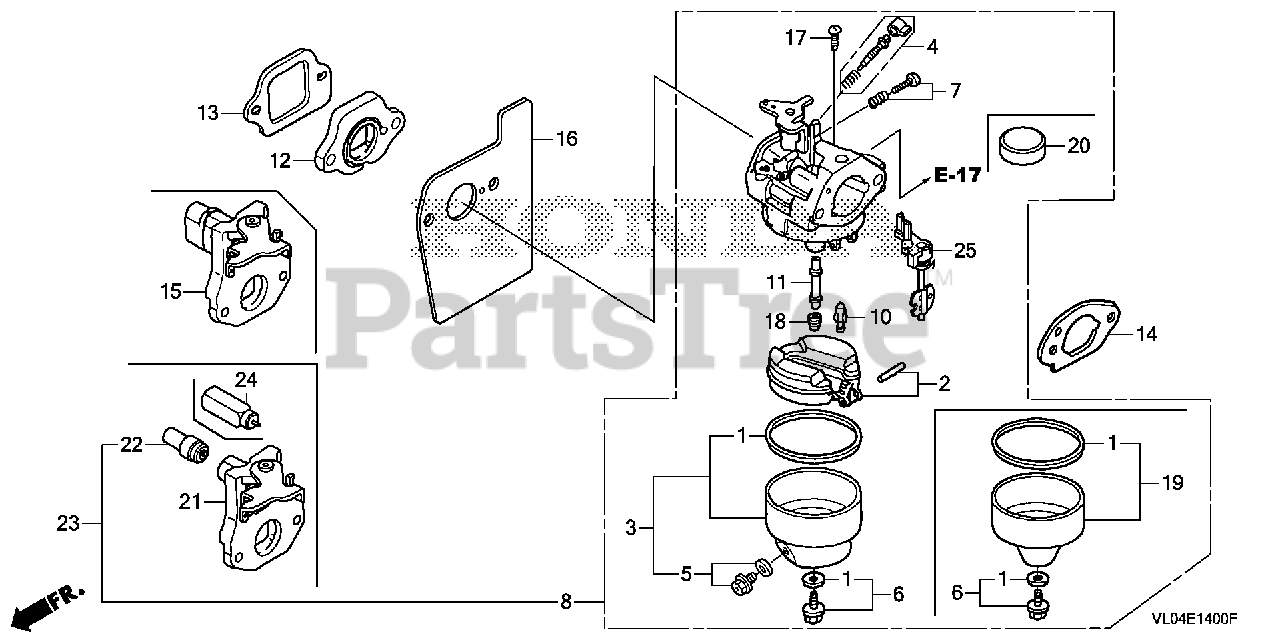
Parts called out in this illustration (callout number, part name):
1	GASKET SET
4	SCREW SET (CARBURETOR NO.)
6	SCREW SET
7	SCREW SET (THROTTLE STOP) (CARBURETOR NO.)
8	CARBURETOR ASSY. (BB75J A)
10	VALVE, FLOAT
11	NOZZLE, MAIN (CARBURETOR NO.)
13	GASKET, INSULATOR
14	GASKET, CARBURETOR (CHOKE SIDE)
16	GUIDE, AIR
17	SCREW, PAN (5X6)
18	JET, MAIN (#62) (CARBURETOR NO.)
18	JET, MAIN (#60) (CARBURETOR NO.)
18	JET, MAIN (#65) (CARBURETOR NO.)
19	CHAMBER SET, FLOAT (CARBURETOR NO.)
20	CAP, CHOKE DUST (CARBURETOR NO.)
21	CONTROL ASSY., CHOKE
24	THERMO WAX ASSY.
